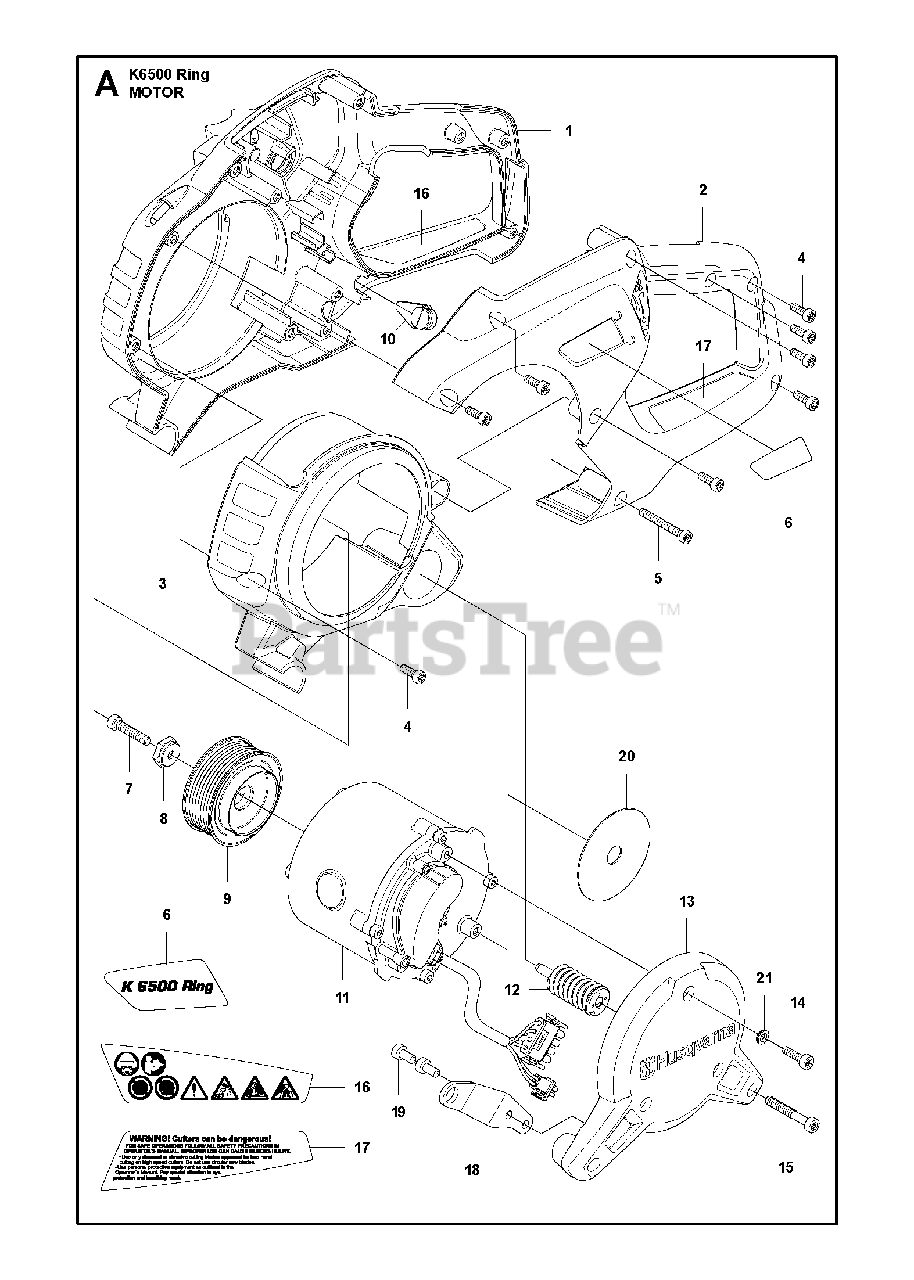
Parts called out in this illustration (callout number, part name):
4	SCREW ITXSCT
7	SCREW ITXSCM
12	ANTIVIBRATION ELEMENT
14	SCREW ITXSCM
15	SCREW ITXSCM
19	SCREW ITXSCT
